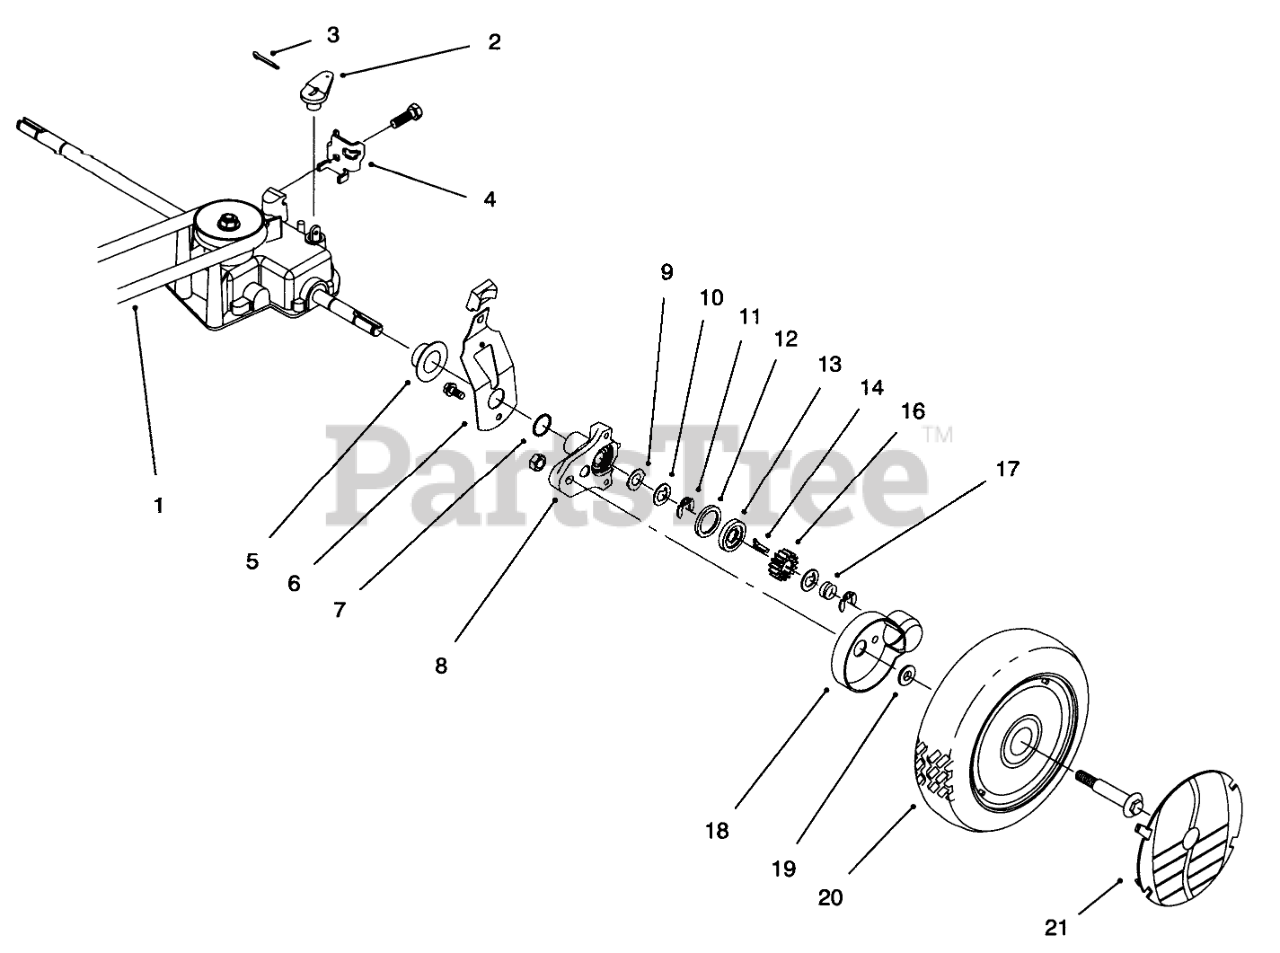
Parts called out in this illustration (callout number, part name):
1	V-BELT E
2	LEVER-SHIFT
3	PIN-COTTER
4	CLAMP-CABLE
5	CAP-END
6	SPRING ARM ASM
7	O-RING
8	PIVOT ARM ASM
9	WASHER-ARM, PIVOT
10	WASHER-THRUST, KEYED
11	RING-CLIP, LOCKING
12	RING-FRICTION
13	WASHER-CLUTCH
14	KEY-ROCKING, LH
16	GEAR-PINION
17	SPRING-COMPRESSION
18	COVER-WHEEL
19	SPACER-COVER, WHEEL
20	WHEEL AND TIRE ASM (W/GEAR)
21	WHEEL COVER
